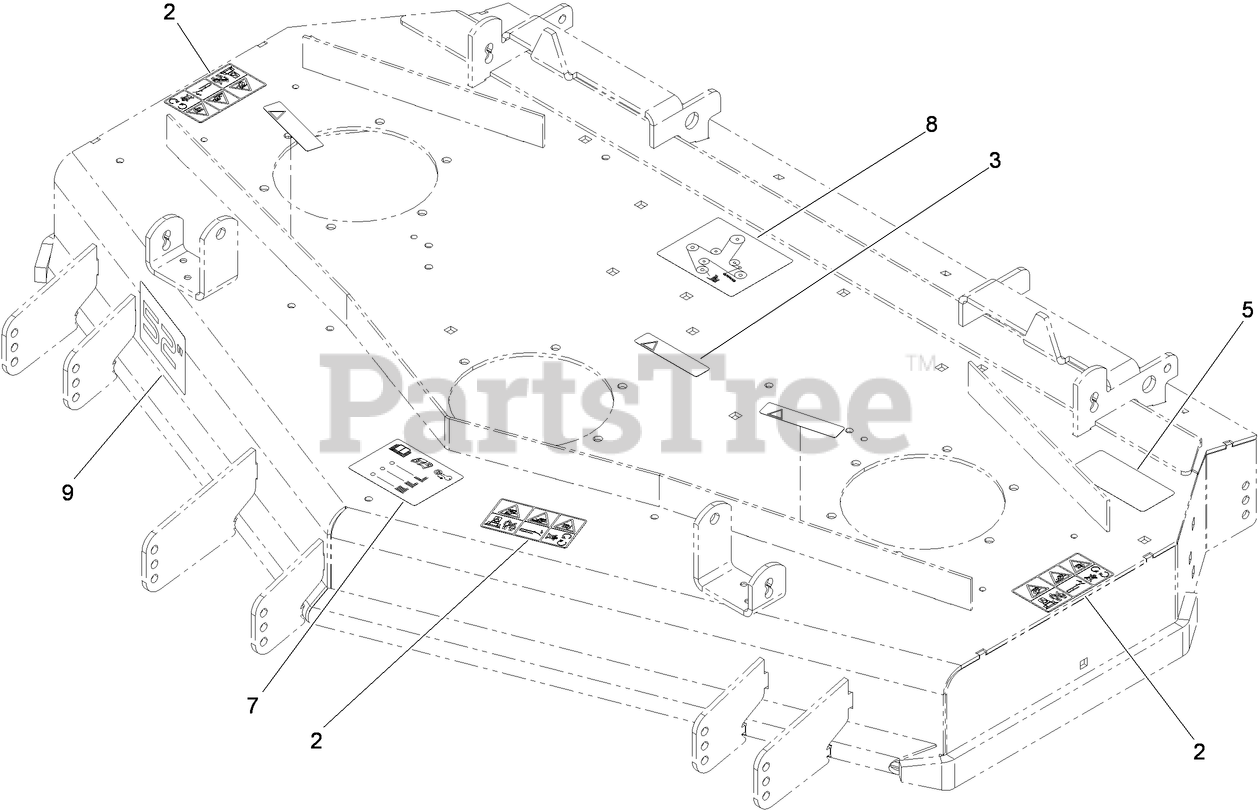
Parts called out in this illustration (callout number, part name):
2	DECAL-DANGER
3	DECAL-WARNING
5	DECAL-TORQUE, BLADE BOLT
7	DECAL-SCALP, ANTI
8	DECAL-ROUTING, BELT
